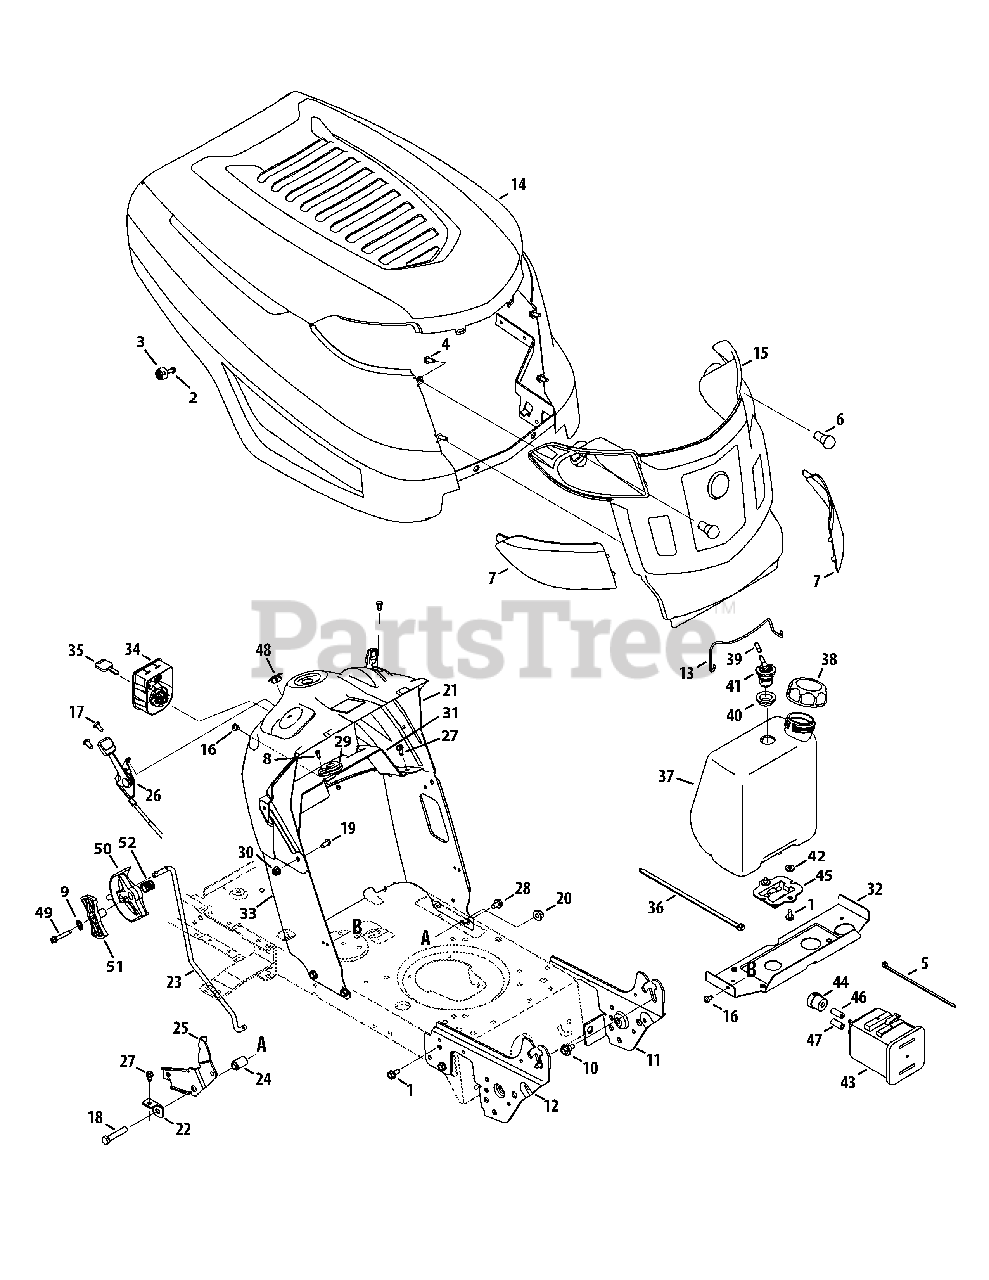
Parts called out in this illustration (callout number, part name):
1	Screw 5/16-18 x .750
2	Screw, #12-16 x 1.25
3	K-Style Bumper
4	Screw, 1/4 x .750
5	Cable Tie
6	Miniature lamp 12V socket
7	Grill Lens - LH
7	Grill Lens - RH
8	Screw, #10-16 x .500
9	Lock Washer, 1/4
10	Shoulder Screw .43 x .29
11	Suppport Bracket LH
12	Suppport Bracket RH
16	Screw, 1/4-20 x .500
17	Screw 1/4-20 x .500
18	Hex Screw 3/8-16 x 2.00
19	Hex Screw, 5/16-18 x .625
20	Flange Lock Nut 3/8-16
21	Dash, Upper
22	Speed Latch Tab
23	Speed Control Rod
24	Flange Spacer .39 x .671 x 1.095
25	Transmission Speed Latch
26	Throttle/Choke Control Cable
27	Tap Screw, 1/4-20, 0.625
28	Screw 5/16-18 x .625
29	Bearing, .628 ID x 1.36
30	Flange lock Nut 5/16-18
31	Bracket, Steering Support
32	Gas Tank Support Bracket
33	Dash, Lower, No WNDW
34	Key Switch Module
35	Key, Assembly
36	Cable Tie
37	Fuel Tank, 1.36 Gallon
38	Fuel Cap
38	Fuel Cap, CARB
39	Hose Vent, 3/16
40	Rubber Grommet
41	Rollover Valve
42	Washer, Flat, .344 x .750 x .120
43	Canister, Carbon, 5 Gallon
44	Filter, Vent, Canister
45	Bracket., Adapter, Canister
46	Hose, Fuel, Low Perm., White
47	Hose, Fuel, Low Perm., Yellow
48	Choke Plug
49	Hex Washer Screw, 1/4-20 x 1.50
50	Shift Lever
51	Index Control
52	Compr. Spring, .72 OD x .78
